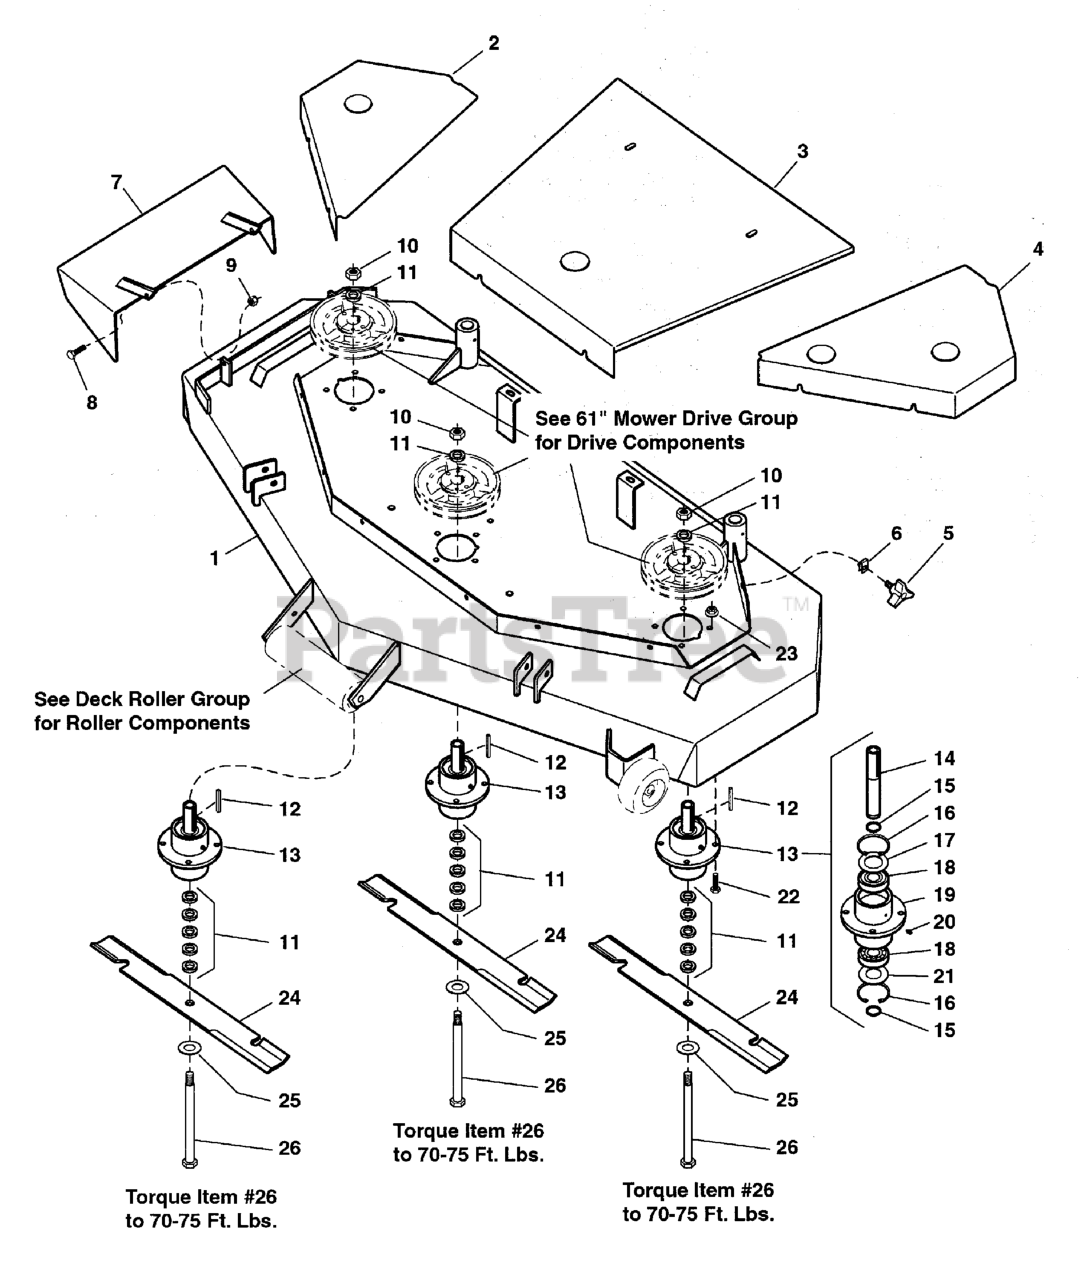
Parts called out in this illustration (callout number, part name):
1	61" MOWER HOUSING ASSEMBLY
2	SPINDLE COVER, RH
3	SPINDLE COVER, Center
4	SPINDLE COVER, LH
5	KNOB
6	BODY CLIP, 5/16-18-7GA MATERIAL
7	CHUTE, DISCHARGE WELDMENT
8	BOLT, 5/16-18 X 1 GD5 YZ
9	NUT, 5/16-18 Hex Nylon Lock
10	NUT, 5/8-11 Hex
11	SPACER, .63 x 1.06 x .23
12	KEY, 1/4 SQ. X 2-1/2
13	SPINDLE ASSEMBLY, Complete
14	SPINDLE SHAFT
15	SNAP RING, External
16	SNAP RING, Internal
17	SPINDLE WASHER, Top
18	BEARING
19	SPINDLE HOUSING
20	GREASE FITTING
21	SPINDLE WASHER, Bottom
22	BOLT, 5/16-18 x 1-1/4
23	NUT, 5/16-18 HEX SERRATED FLANGE (LARGE)
24	MOWER BLADE, 21"
25	WASHER, 5/8" USS
26	BOLT, 5/8-11 x 9-1/2
